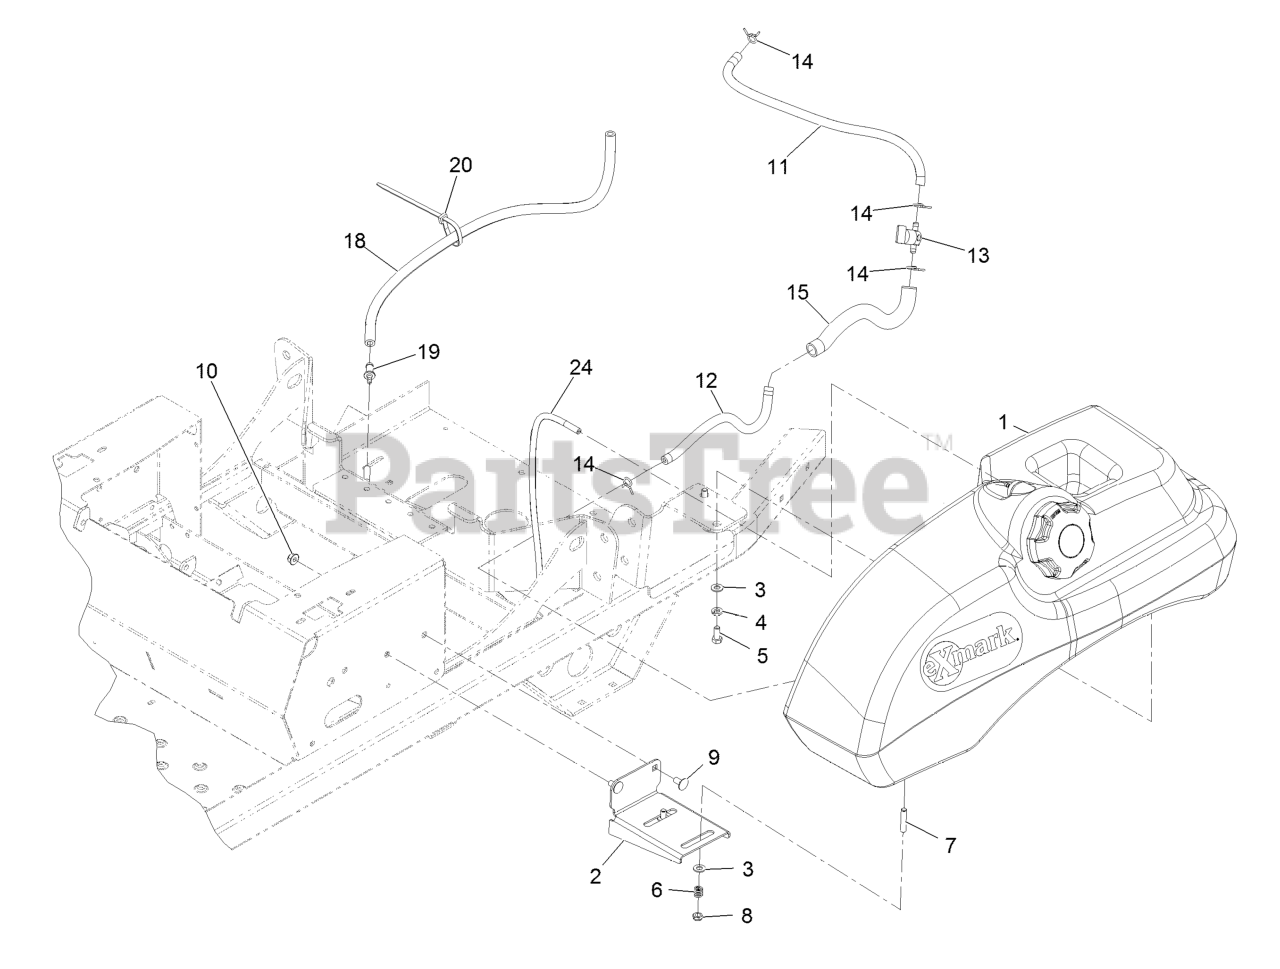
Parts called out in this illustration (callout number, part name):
1	ASM-FUEL TANK
2	BRACKET-TANK AND FENDER
3	WASHER-PLAIN
4	WASHER-LOCK
5	SCREW-HH
6	SPRING-TANK, FUEL
7	STUD
8	NUT-LOCK, NI
9	SCREW-CARR
10	NUT-HF, NI
11	HOSE-FUEL
12	HOSE-FUEL
13	VALVE-FUEL
15	CONDUIT-FUEL LINE
18	HOSE-FUEL
19	FITTING-ORIFICE, STRAIGHT
20	TIE-PLASTIC
24	HOSE,EMISSIONS
